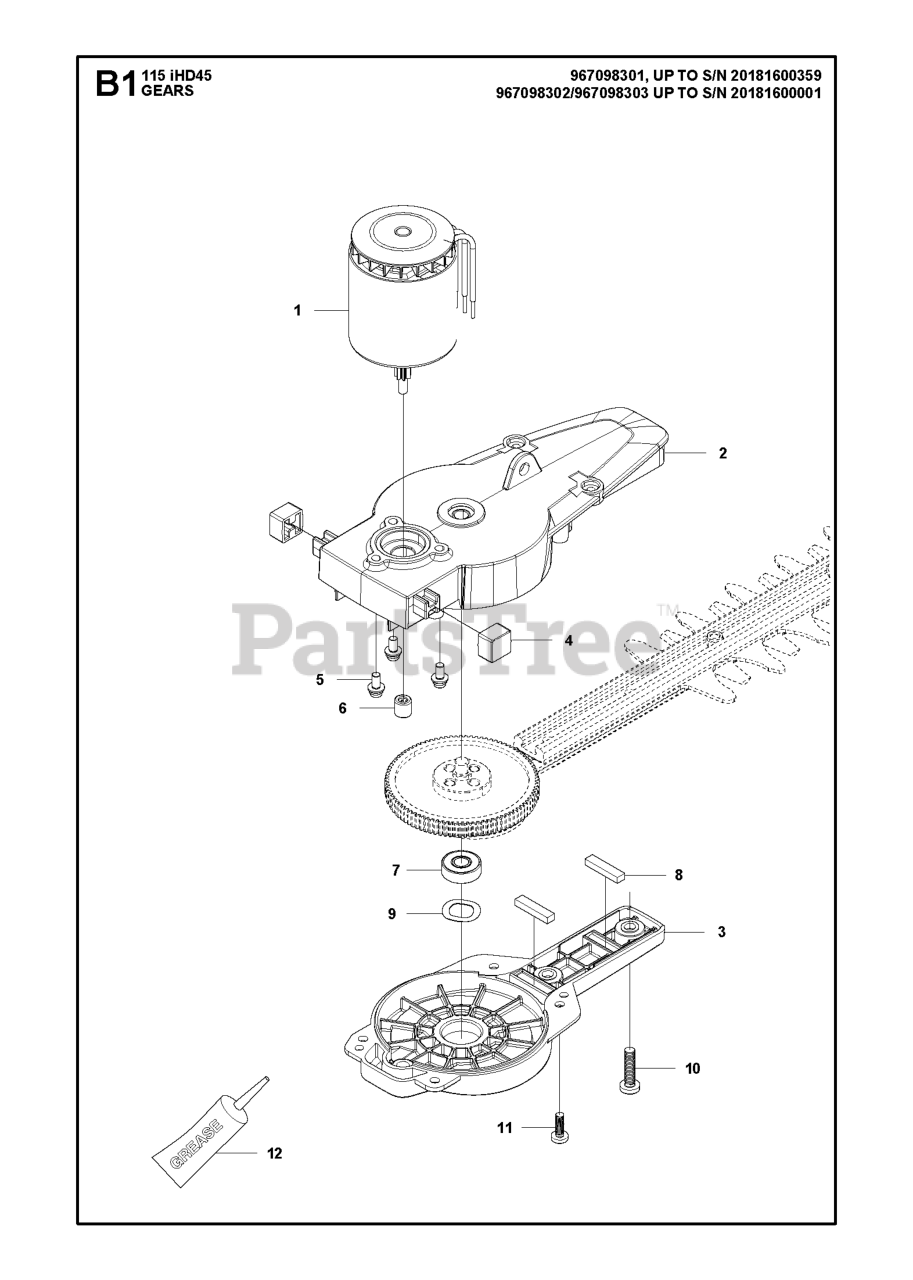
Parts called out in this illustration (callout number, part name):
1	MOTOR BLDC 115IHD55
3	COVER GEAR BOX
4	SHOCK ABSORBING
6	NEEDLE BEARING
7	BALL BEARING
8	PAD DUSTPROOF
9	SPRING WASHER
10	SCREW M5X20
11	SCREW M4X12
12	GREASE 20G HEDGE TRIMMER GEAR
